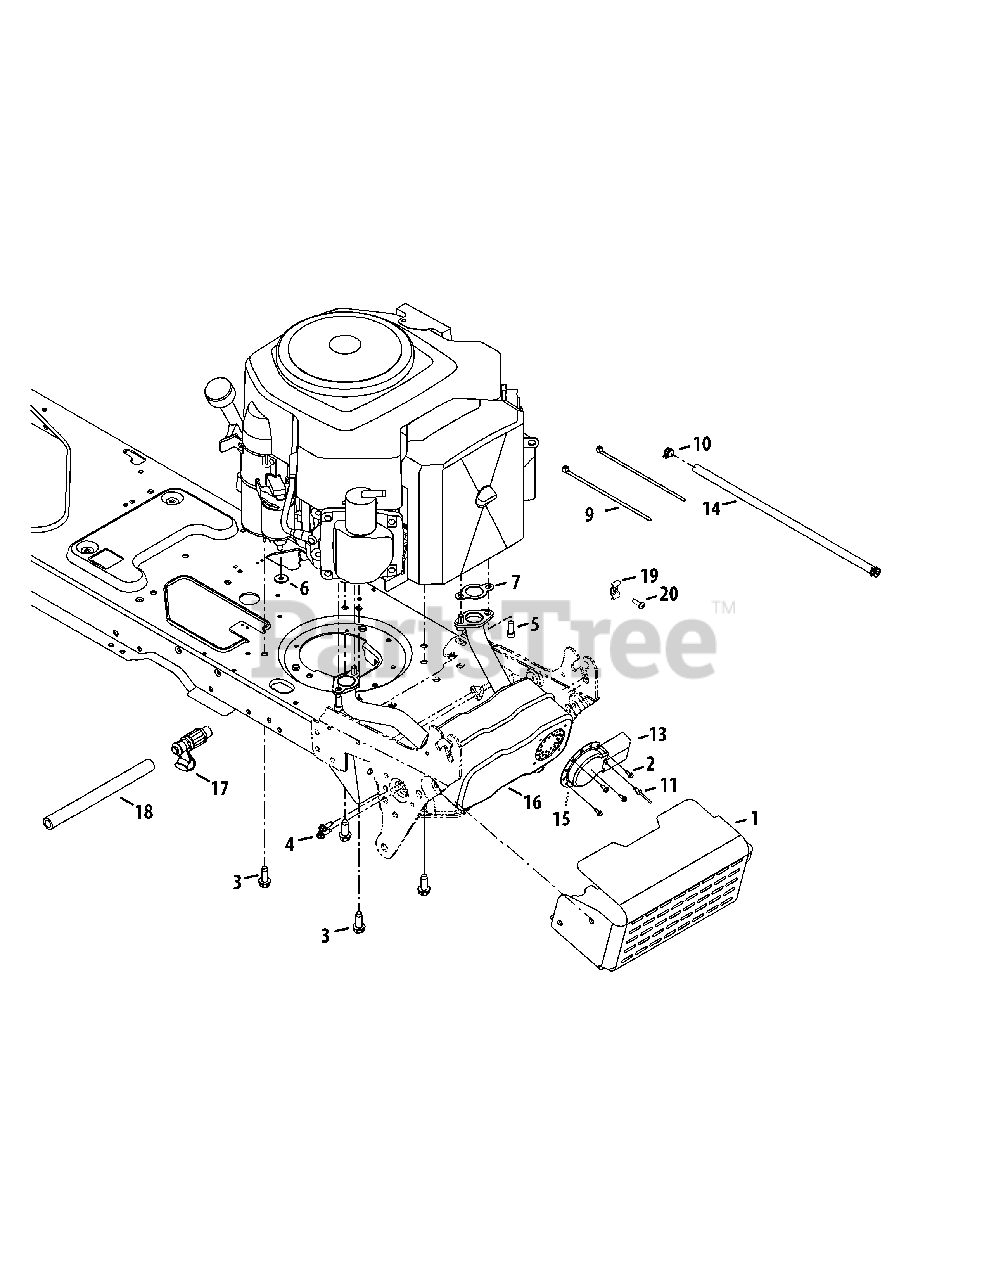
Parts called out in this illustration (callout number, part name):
1	Muffler Shield
2	Hex Wash HD AB S-Tapp Scr #8-.50
3	Hex Wash S-Tapp Scr 3/8-16 x 1.0
4	Thd Form ing Scr. 1/4-20 x .75 Lg.
5	Socket HD Cap Scr. 5/16-18 x .75
6	Sems Nut 1/4-20
7	Gasket
11	Rivot, Pop, .188 x .3
12	Flat Washer .385 ID x .87 OD x .06
13	Muffler Deflector
14	Fuel Hose; Low Permeation, 51" Lg.
15	Muffler Deflector Long
16	Muffler
18	Oil Drain Hose
19	Clamp
20	Torx Tap. Screw M5 x 0.8
